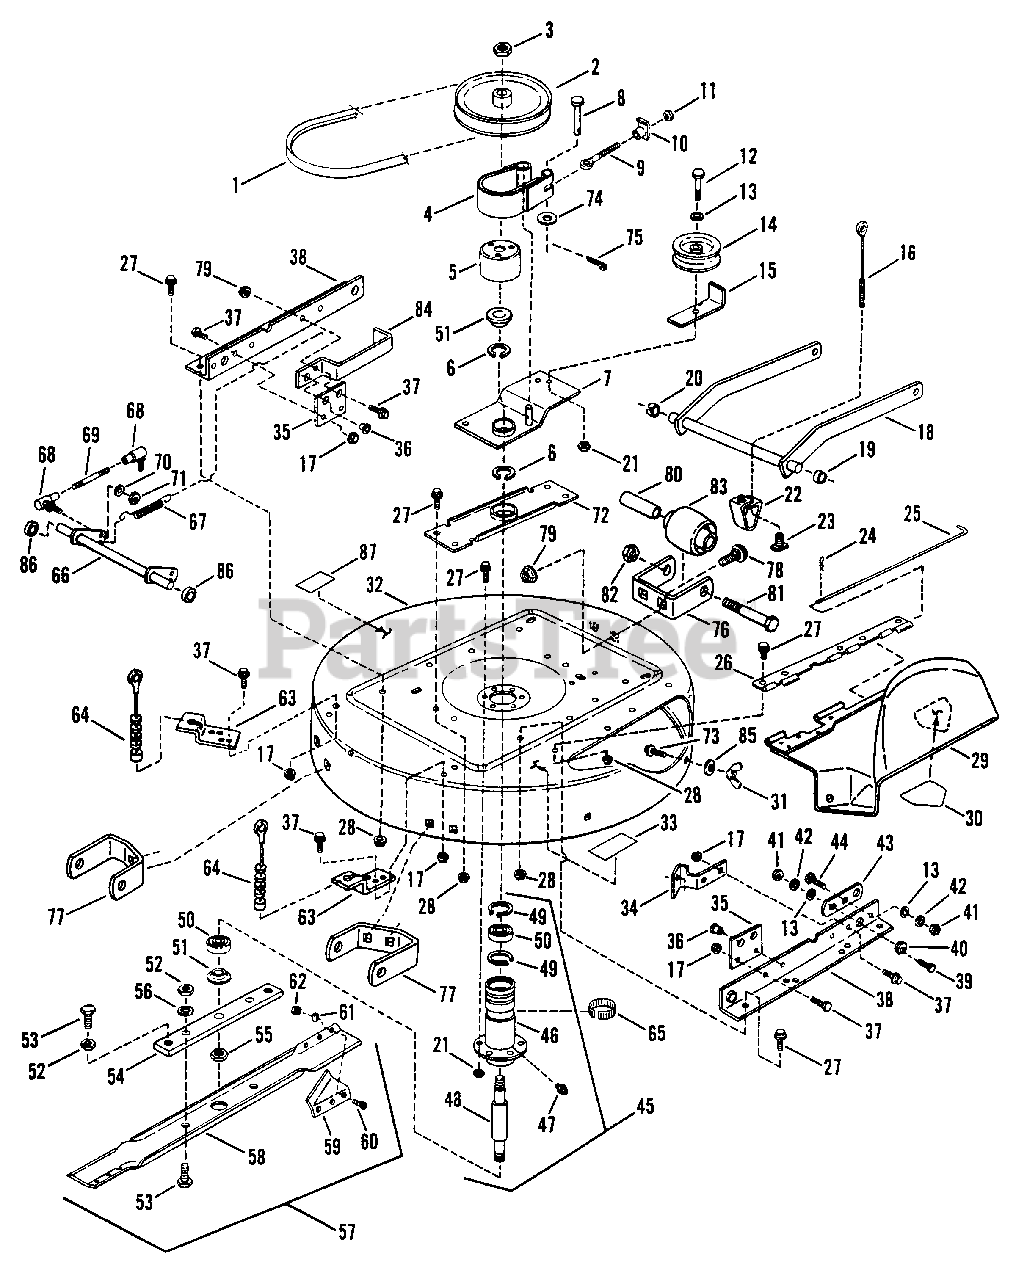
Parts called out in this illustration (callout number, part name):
1	BELT, 33" Drive Kevlar (A-59 61" OD)
2	PULLEY, 8" O.D.
3	NUT, 3/4-16 Hex Jam
4	BAND, Brake Assembly
5	DRUM, Brake
6	RING, 2" External Retaining
7	ARM, Idler
8	PIN, 1/4 x 1 1/4" Clevis
9	BOLT, 1/4-20 Eye
10	NUT, 1/4-20 Tee
11	NUT, 1/4-20 Hex GR 5 YZ
12	SCREW, 3/8-24 x 1 1/2" Hex Head Cap
13	WASHER, 3/8 SAE
14	PULLEY, Idler, 4.12 O.D.
15	GUIDE, Belt
16	CABLE, Front Lift 6.12"
17	NUT, 5/16-18 Hex Flange Lock
18	LIFT, Front Arm
19	RING, Red (Right Side)
20	RING, Black (Left Side)(5/8" ID x .44" Wide)
21	NUT, 3/8-24 Hex Lock
22	BRACKET, Front Lift Hanger
23	T-NUT, 5/16-18
24	PIN, Hair 3/32" x 1.5"
25	PIN, Hinge
26	HINGE, Deflector
27	BOLT, 3/8-16 x 3/4" Hex Flange Lock
28	NUT, 3/8-16 Hex Flange Lock
29	ASSEMBLY, Deflector
30	DECAL, Danger (Cut Finger)
31	WING-NUT, 5/16-18
32	DECK, Cutting, 33"
33	DECAL, Caution (Deflector)
34	ANCHOR, Brake
35	BRACKET, Cross-Shaft
36	BEARING, Cross-Shaft Bracket
37	BOLT, 5/16-18 x 1/2" Hex Flange Lock
38	RAIL, Side
39	SCREW, 3/8-16 x 1" Hex Head Cap
40	ECCENTRIC, Leveling
41	NUT, 3/8-16 Hex
42	WASHER, 3/8 Split Lock
43	LINK, Adjustment
44	BOLT, 3/8-16 x 3/4" Carriage
45	ASSEMBLY, Spindle
46	HOUSING, Spindle 5.575" Tall
47	FITTING, Lube (Press into .187" hole, no ball)
48	SPINDLE, 33" Mower Deck 8.26" Long
49	RING, Retaining EXT 1.75"
50	BEARING, Spindle
51	WASHER, Spindle
52	NUT, 1/4-20 Hex Jam
53	SCREW, 1/2-20 Hex Head Cap
54	HOLDER, Blade
55	NUT, 5/8-18 Hex Lock
56	WASHER, 1/2 Int. Tooth Lock
58	BLADE, 33" Mower Deck
59	AIR-LIFT
60	SCREW, 5/16-24 x 11/16" Machine
61	WASHER, 5/16 Internal Tooth Lock
62	NUT, 5/16-24 Hex
63	BRACKET, Rear Lift
64	CABLE, Support (4.25", 8 Spacers)
65	RING, Tolerance 2.0"
66	CROSS-SHAFT
67	SPRING
68	BALL-JOINT
69	LINK, Ball Joint
70	WASHER, 1/4 Int. Tooth Lock
71	NUT, 1/4-28 Hex
72	BRACE, Spindle
73	BOLT, 5/16-18 x 3/4" Short Neck Carriage
74	WASHER .28 x .63 x .065 YZ
75	COTTER-PIN, 3/32 x 3/4"
76	BRACKET, Gage Wheel (Front)
77	BRACKET, Gage Wheel (Rear)
78	BOLT, 5/16-18 x 1/2" Short Neck Carriage
79	NUT, 5/16-18 Hex Flange Lock
80	SPACER .625 OD x .423 ID x 3" L
81	SCREW, 3/8-24 x 3 3/4" Hex Head Cap
82	NUT, 3/8-24 Hex Lock
83	WHEEL, Gage
84	GUIDE, Belt
85	WASHER, 5/16 Flat
86	SPACER
87	DECAL, Caution (Rotating Blades)
87	DECAL 33" (RLT140H33) (No longer available)
87	DECAL Deep Drawn (RLT140H33) (No longer available)
